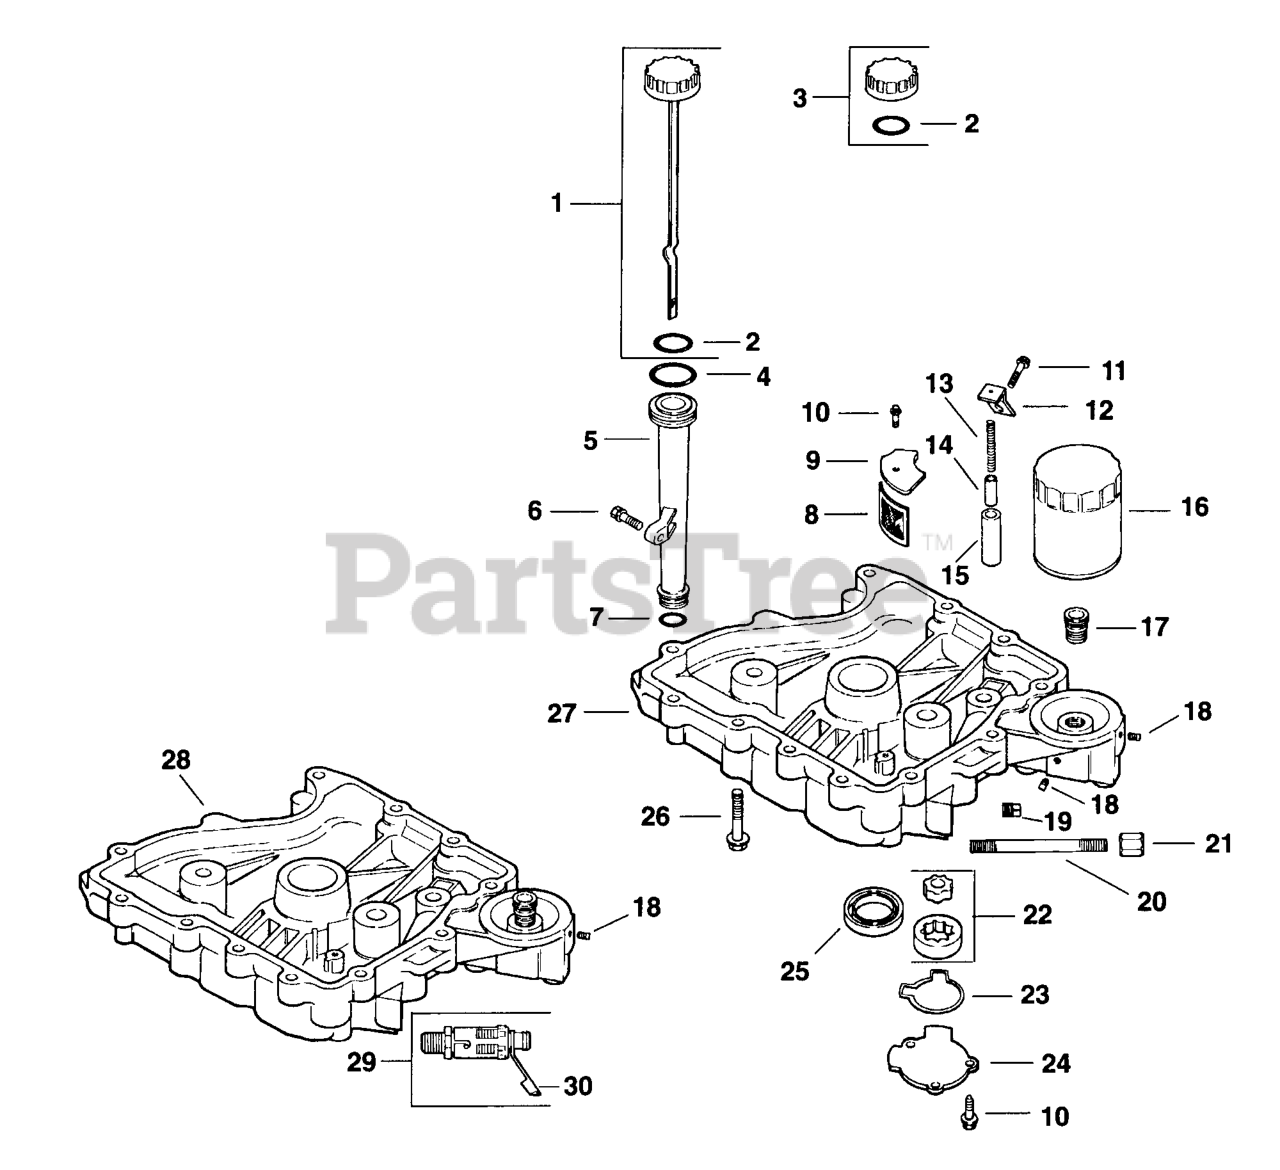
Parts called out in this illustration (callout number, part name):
1	DIPSTICK/CAP ASSY (YELLOW) - DISCONTINUED
2	O-RING - USE 25 153 02-S
3	KIT, OIL FILL CAP (YELLOW)
4	O-RING, UPPER OIL FILL TUBE
5	TUBE, OIL FILL USE 25 123 07-S
6	Screw, hex. flange M5x0.8x20
7	O-RING, LOWER OIL FILL TUBE
8	SCREEN - USE 25 162 07
10	Screw, hex. flange M5x0.8x16
11	SCREW, FLG M10X1.5X25
12	VALVE - USE 25 462 09
13	VALVE - USE 25 462 09
14	VALVE - USE 25 462 09
15	VALVE - USE 25 462 09
16	OIL FILTER
17	NIPPLE
18	PLUG, PIPE USE 25 139 52-S
19	PLUG, SQ HD PIPE 3/8" USE 25 139 57-S
20	NIPPLE - USE 12 136 11
21	CAP, PIPE
22	PUMP ASSEMBLY, OIL - DISCONTINUED
23	SEAL, OIL-PUMP COVER
25	SEAL, OIL
26	Screw, hex. flange M8x1.25x45
27	PAN - USE 12 199 21
